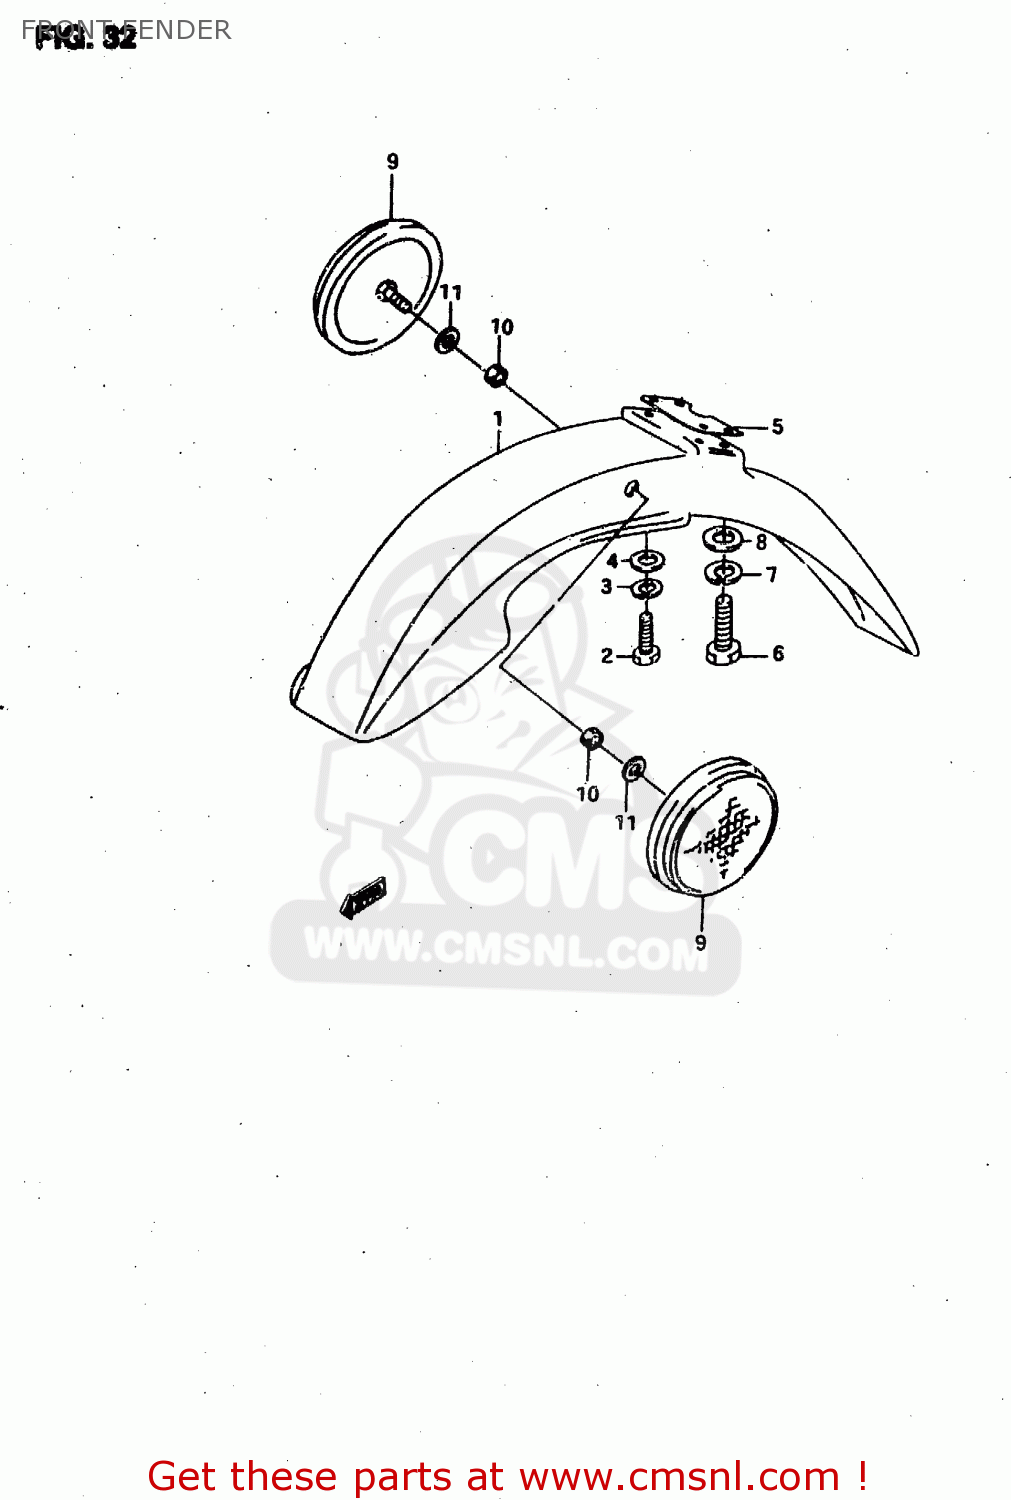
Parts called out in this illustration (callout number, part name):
1	FENDER, FRONT (WHITE)
2	BOLT
3	LOCK WASHER
4	WASHER(6.5X18X1.6)
5	FRONT FENDER
6	BOLT
7	LOCK WASHER
8	WASHER
9	REFLECTOR
10	NUT, LICENSE
11	WASHER
